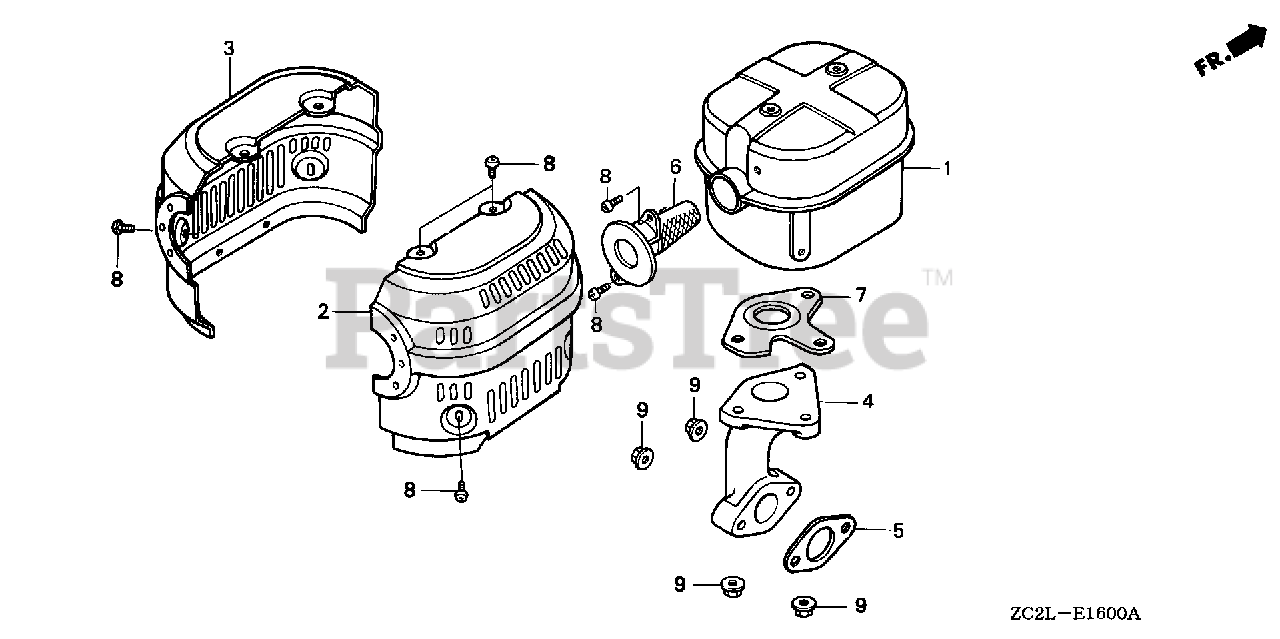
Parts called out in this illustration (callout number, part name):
2	PROTECTOR, R. MUFFLER
3	PROTECTOR, L. MUFFLER
5	GASKET, EX. PIPE
6	ARRESTER, SPARK
7	GASKET, MUFFLER (ARRESTER) (NIPPON LEAKLESS)
8	SCREW, TAPPING (5X8)
9	NUT, FLANGE (8MM)
